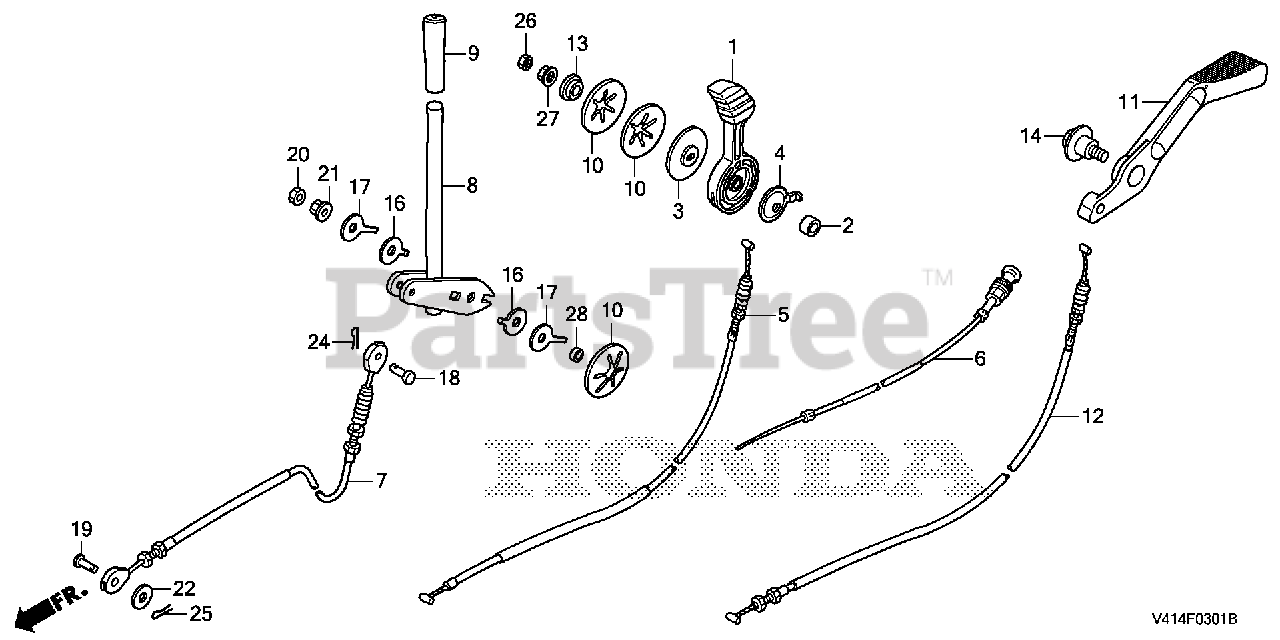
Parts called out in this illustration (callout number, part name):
1	LEVER, THROTTLE
2	COLLAR, THROTTLE PIN
3	PLATE, THROTTLE LEVER
4	SEAT, SPRING
5	CABLE, THROTTLE
6	CABLE, CHOKE
7	CABLE, CHANGE
8	LEVER, CHANGE
9	GRIP, CHANGE LEVER
10	SPRING, ADJUSTING ARM
13	COLLAR, CHUTE GUIDE
15	NUT, NYLON LOCK (6MM)
16	WASHER, FRICTION
17	WASHER, FRICTION SETTING
19	PIN (8X34)
20	NUT, HEX. (8MM)
21	NUT-WASHER (8MM)
22	WASHER, PLAIN (8MM)
23	WASHER, PLAIN (8MM)
24	PIN, SPLIT (1.6X12)
25	PIN, SPLIT
26	NUT, HEX. (6MM)
27	NUT, FLANGE (6MM)
28	TUBE, RUBBER (7.3X12.5X5.5)
